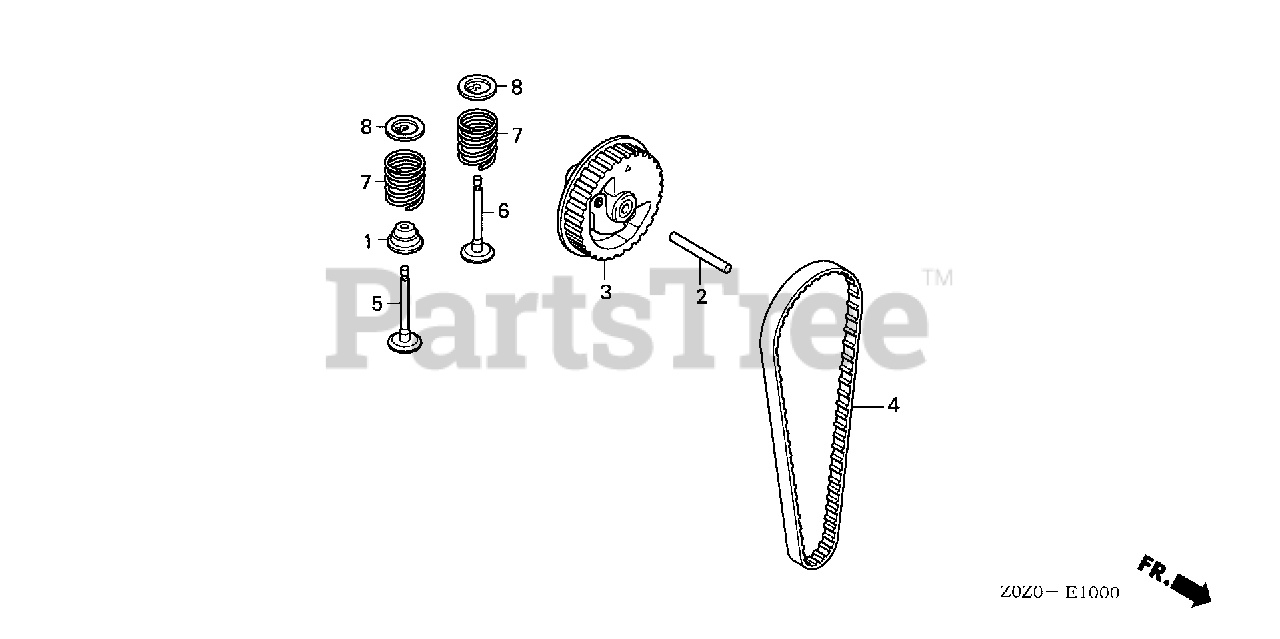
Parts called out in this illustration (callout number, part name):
1	SEAL, VALVE STEM
2	ROLLER (4X31.8)
3	PULLEY, CAMSHAFT
4	BELT, TIMING (76ZU6 G-310)
5	VALVE, IN. (ZI)
6	VALVE, EX. (ZE)
7	SPRING, VALVE
8	RETAINER, VALVE SPRING
